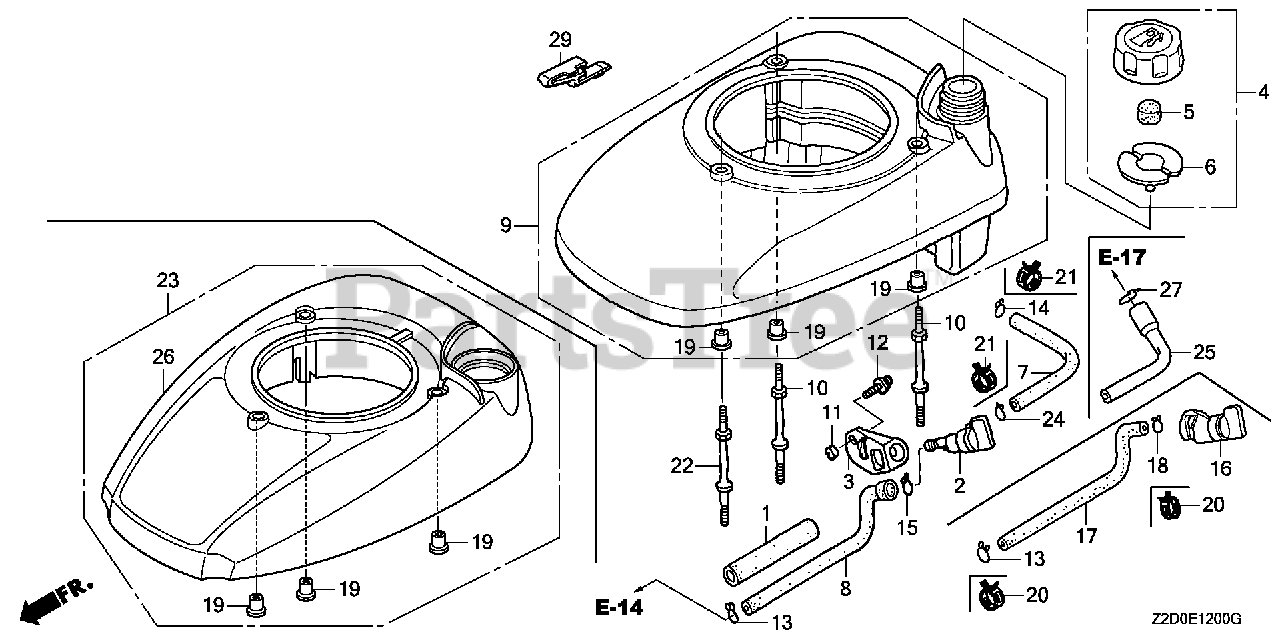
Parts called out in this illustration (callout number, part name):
1	RUBBER, SUPPORTER (107MM)
2	PETCOCK ASSY.
3	BRACKET, PETCOCK
4	CAP ASSY., FUEL TANK
5	SPONGE, FUEL CAP BREATHER
6	GASKET, FUEL CAP
7	TUBE, FUEL TANK
8	TUBE, FUEL
9	COVER, FAN *NH1* (BLACK)
9	COVER, FAN *R280* (POWER RED)
10	BOLT, STUD (H=42.5MM)
11	COLLAR, FUEL PETCOCK
12	SCREW-WASHER (5X10)
13	CLIP, TUBE (B8)
14	CLIP, TUBE (B10)
15	CLIP, TUBE (C9)
19	COLLAR, FAN COVER
22	BOLT, STUD (H=42.5MM)
24	CLIP, TUBE (B10)
